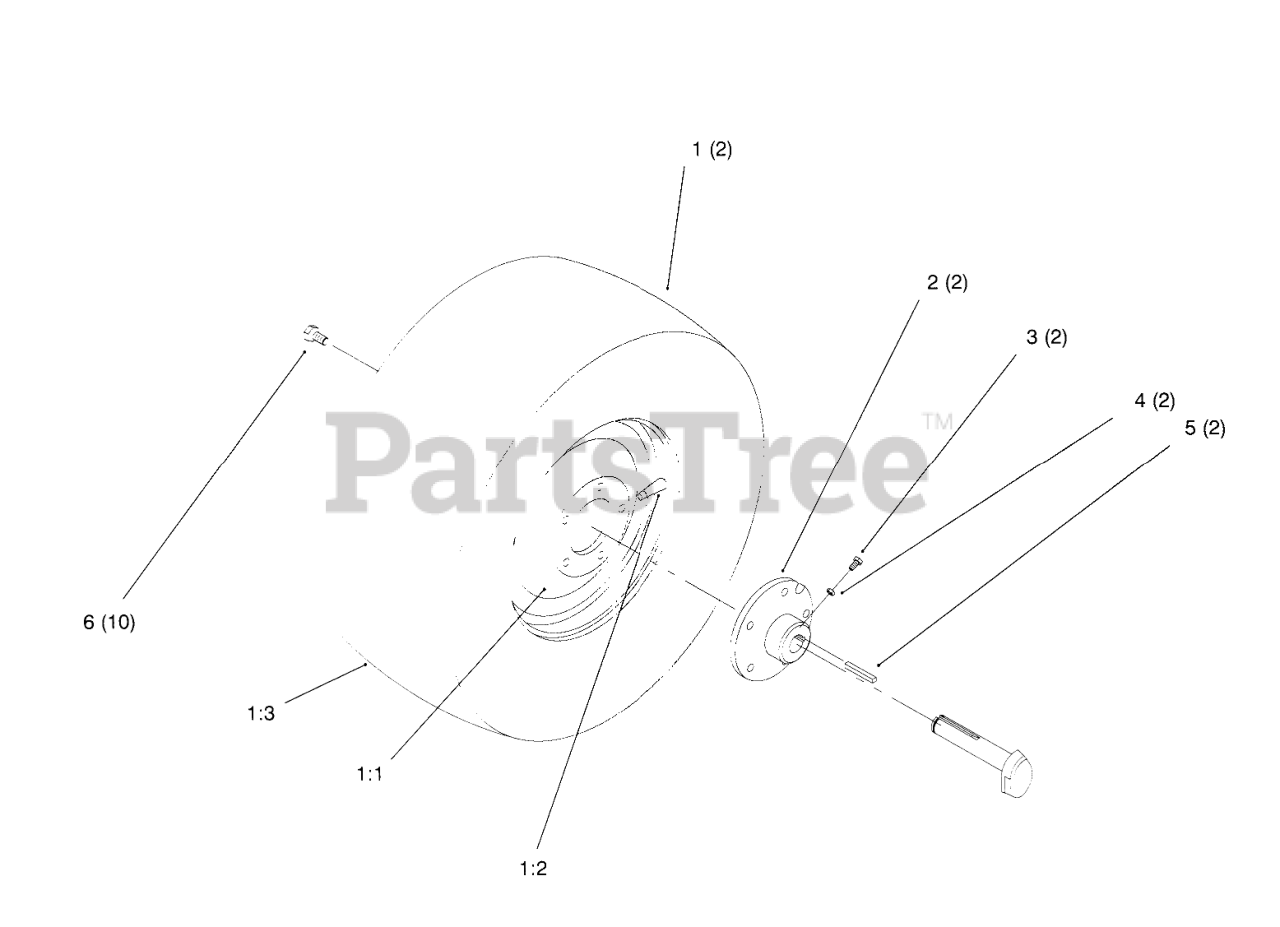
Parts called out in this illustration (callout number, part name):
1:1	WHEEL
1:2	VALVE
1:3	Tire (Only On: 72042,72043,72062,72063)
1:3	Tire (Only On: 72103)
2	HUB-WHEEL
3	SCREW-SET, SQH
4	NUT-JAM
5	KEY-SQUARE
6	BOLT-LUG
